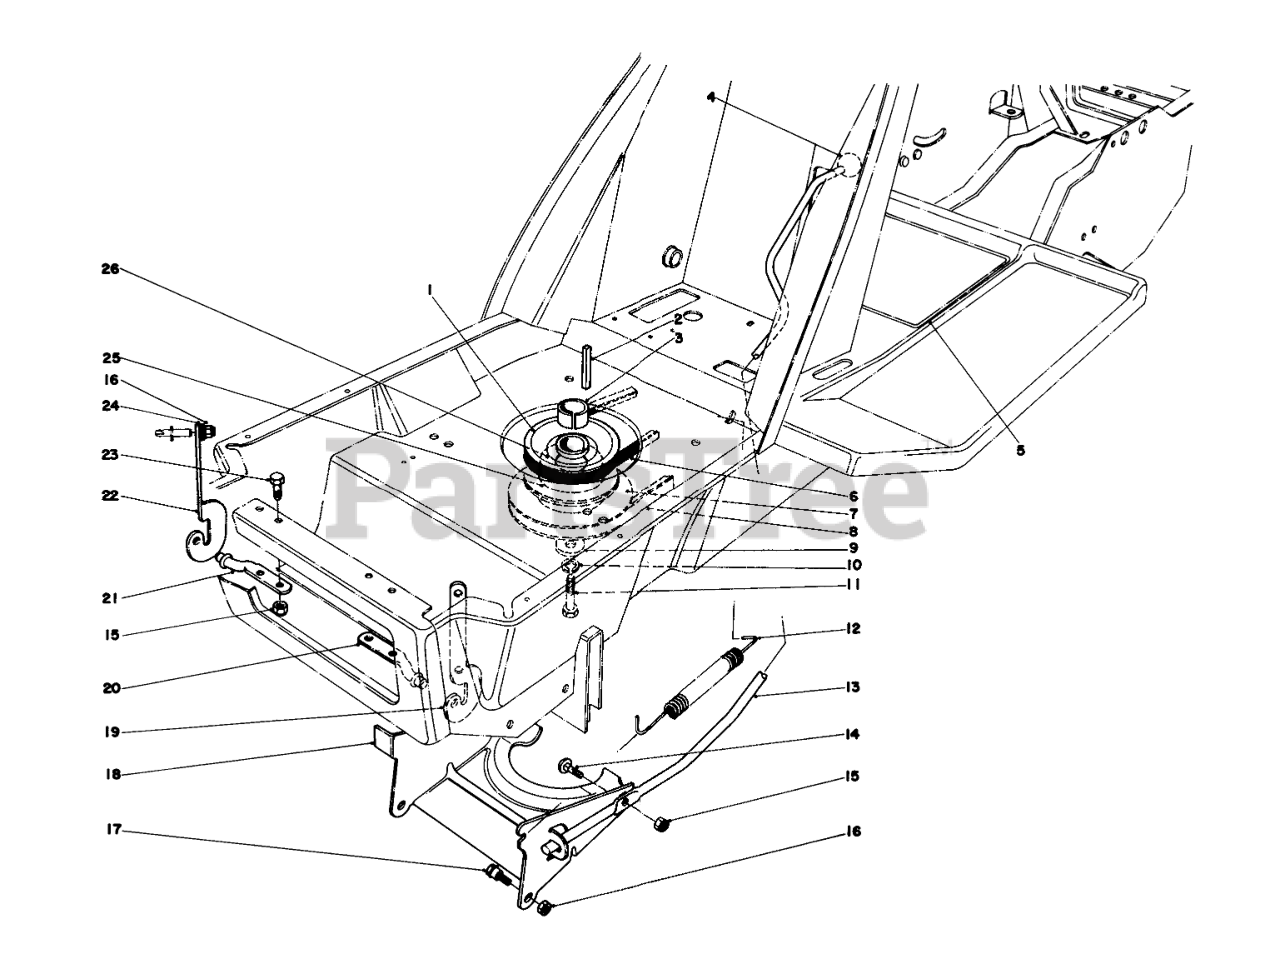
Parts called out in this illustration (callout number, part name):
1	TOP SHEAVE
2	KEY-SQUARE
3	PULLEY SPACER
5	Decal Instruction
6	V BELT
7	Clutch & Brake Decal (Incl. Ref. #25 & 26)
8	V BELT
9	WASHER
10	WASHER-LOCK
11	SCREW-HH
12	TRACTION SPRING
13	Engagement Lever
14	Bolt
15	NUT-LOCK, CONE
16	NUT-LOCK, CONE
17	SCREW-SHOULDER
18	CLUTCH ACTUATOR R
19	L.H. HINGE BRACKET
20	LH HOOD HINGE PIN
21	RH HOOD HINGE PIN
22	RH HINGE BRKT
23	SCREW-HH
24	SCREEN SUPT BRKT
25	CLUTCH PLATTER
26	SPRING WASHER
